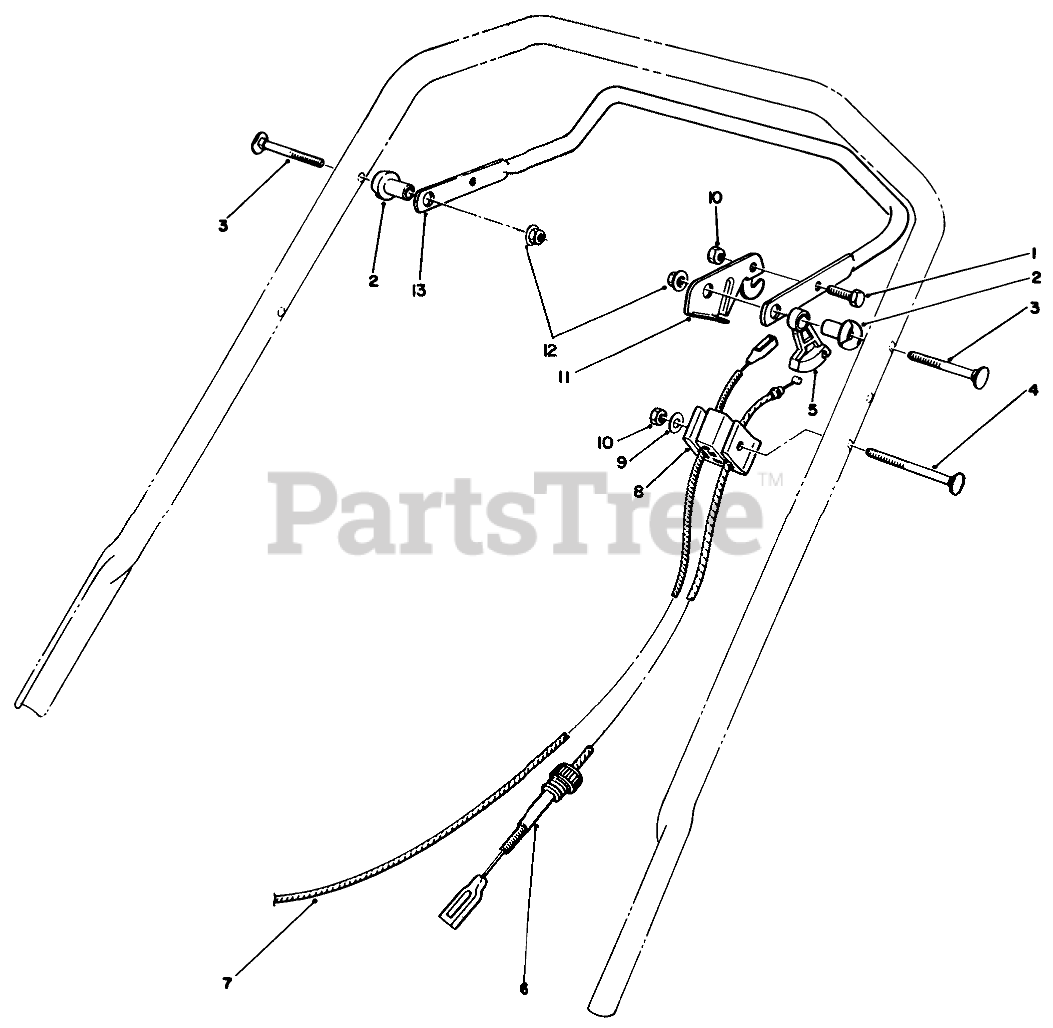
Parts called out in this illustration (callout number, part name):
1	SCREW-HH
2	SPACER-SUPPORT
3	5/16-18 X 2 HNDLE SCREW
4	HANDLE SCREW
5	LEVER-TRACTION
6	CABLE-TRACTION
7	BRAKE CABLE
8	SUPPORT-CABLE
9	WASHER-FLAT
10	NUT-LOCK, NI
11	LEVER-CONTROL
12	NUT-LOCK, NI
13	Bar-Control
